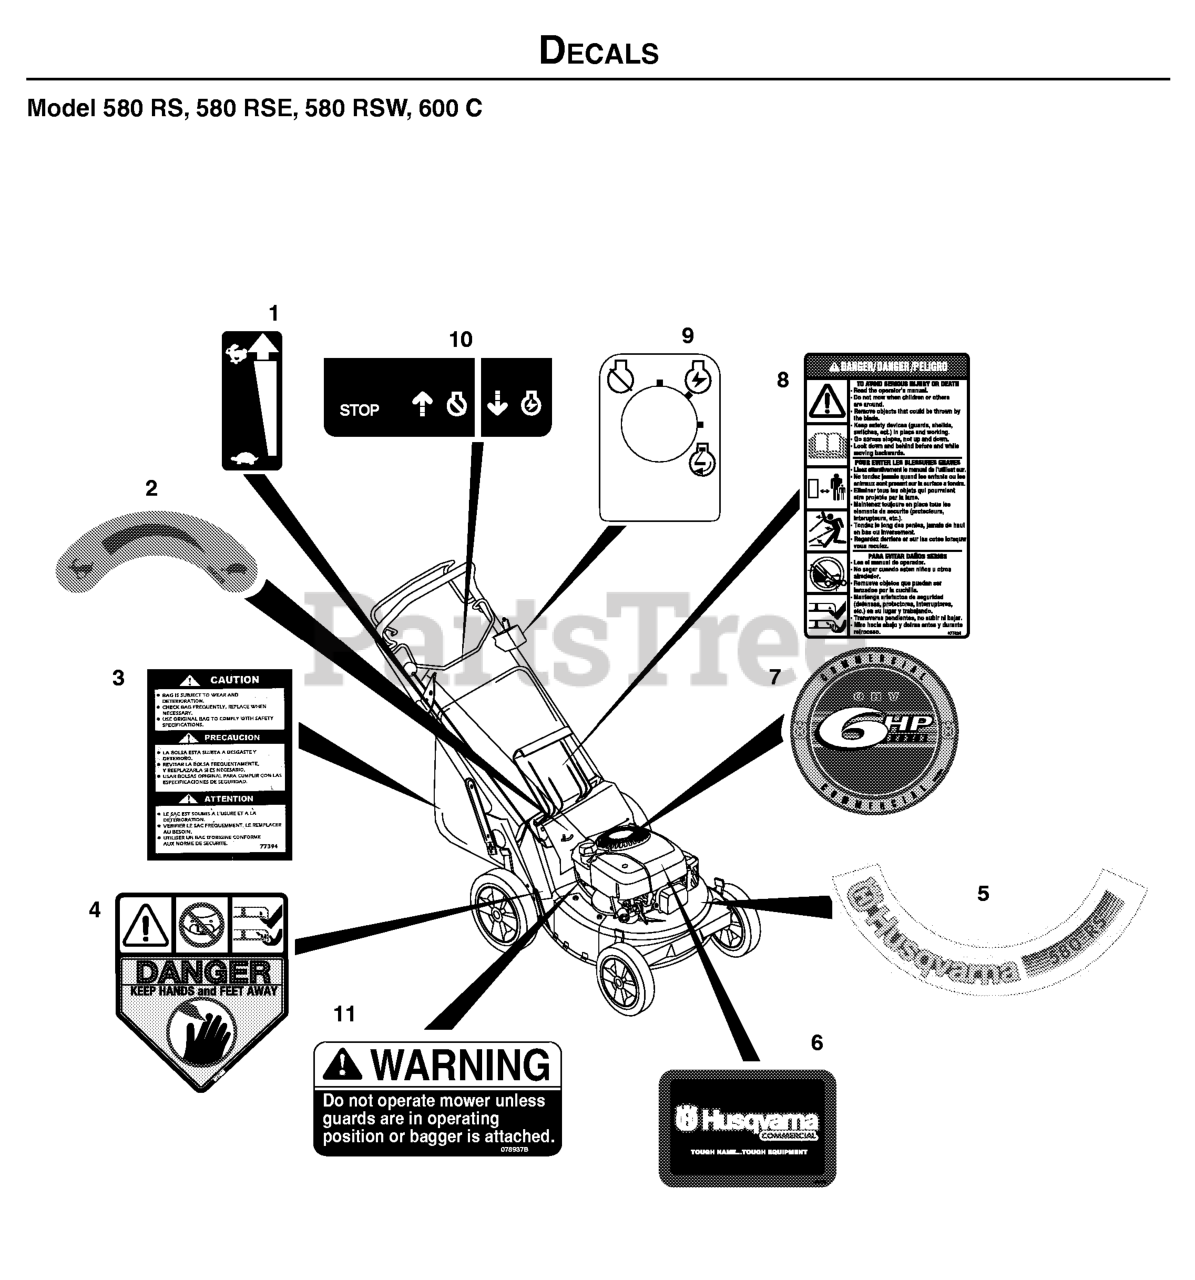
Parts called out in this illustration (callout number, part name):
1	Decal-Speed Control
2	Decal-Swoosh Husqvarna
3	Label-Bagger 21"
4	Decal-Danger
5	Decal-580 RS
6	Decal-Husqvarna & Robins (600 C)
7	Decal-Robin 6HP OHV-Commercial (600 C)
8	Decal-Bilingual Danger
9	DECAL-KEY SWITCH
10	Decal-Engine Control
11	DECAL-WARNING
